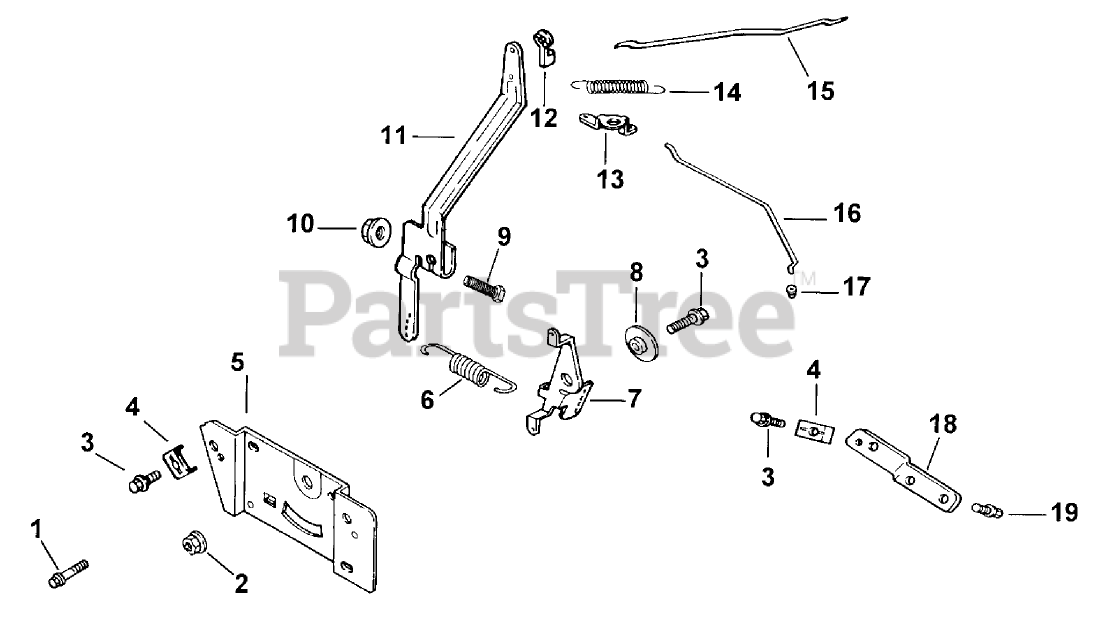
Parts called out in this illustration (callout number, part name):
1	Screw Socket
2	Nut, hex. flange M5x0.8
3	Screw M5x0.8x16 (Only On: 72042, 72063, 72062, 72043)
4	Clamp
5	Plate, control
6	Spring, governor
7	Lever, throttle control
8	Spacer, throttle control
9	Screw
10	Nut
11	Lever, governor
12	Bushing-Linkage
13	Lever, choke-upper
14	Spring, linkage
15	Linkage, throttle
16	Linkage, choke-upper
17	Bushing
18	Bracket, choke mount
19	Screw
